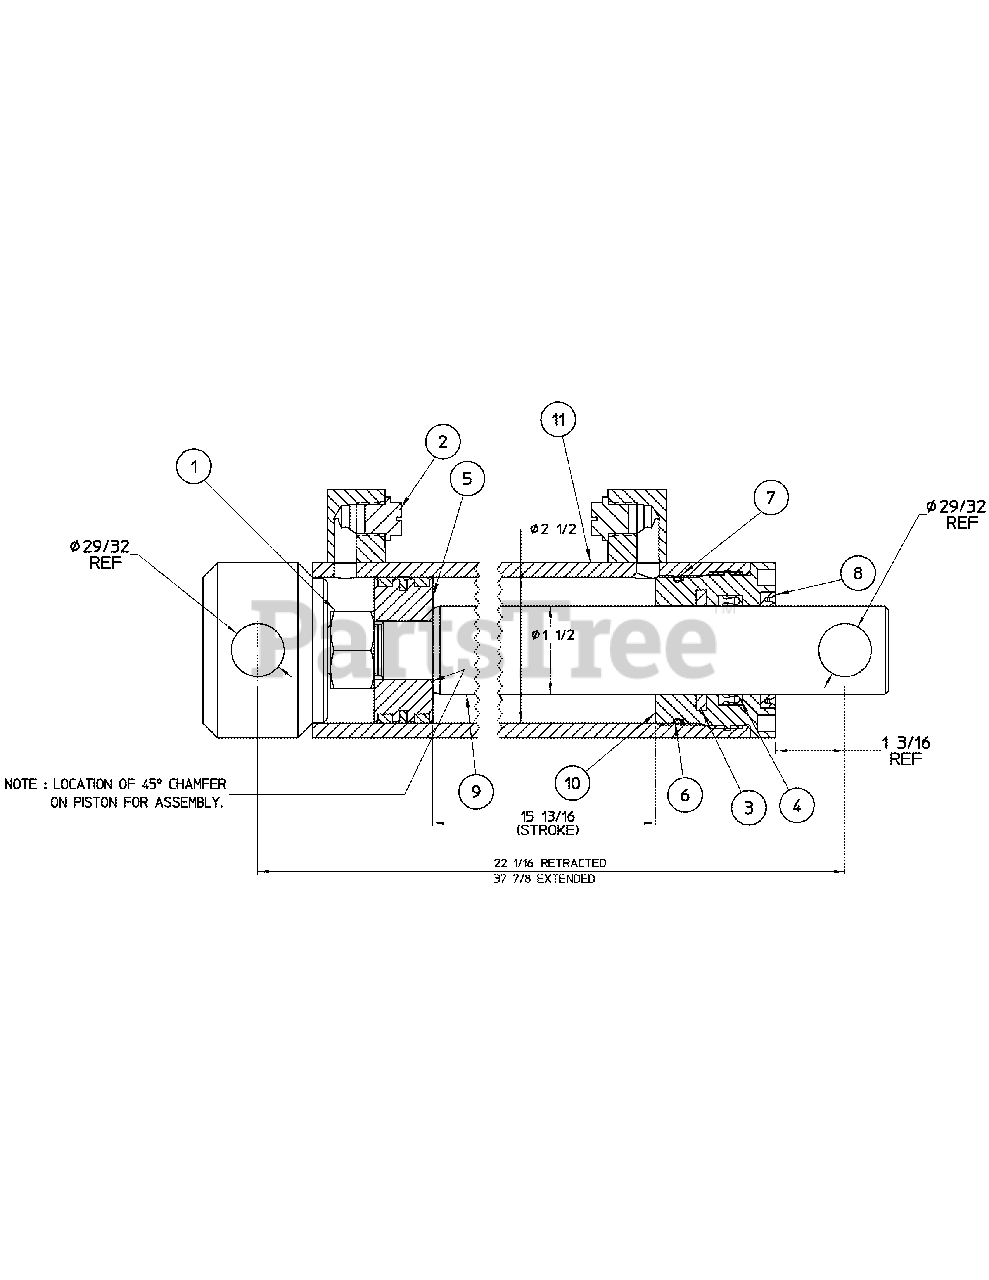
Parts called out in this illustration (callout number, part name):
1	Nut, 7/8" Lock
3	Step Seal
4	Rod Seal
5	Piston
6	O-Ring, 2-9/16" OD x 2-3/8" ID
7	Back-Up Ring, 2.565" OD x 2.393" ID
8	Rod Wiper
9	Piston Rod
10	Gland with O-rings, Back-Up, etc.
11	Cylinder Tube Weldment
